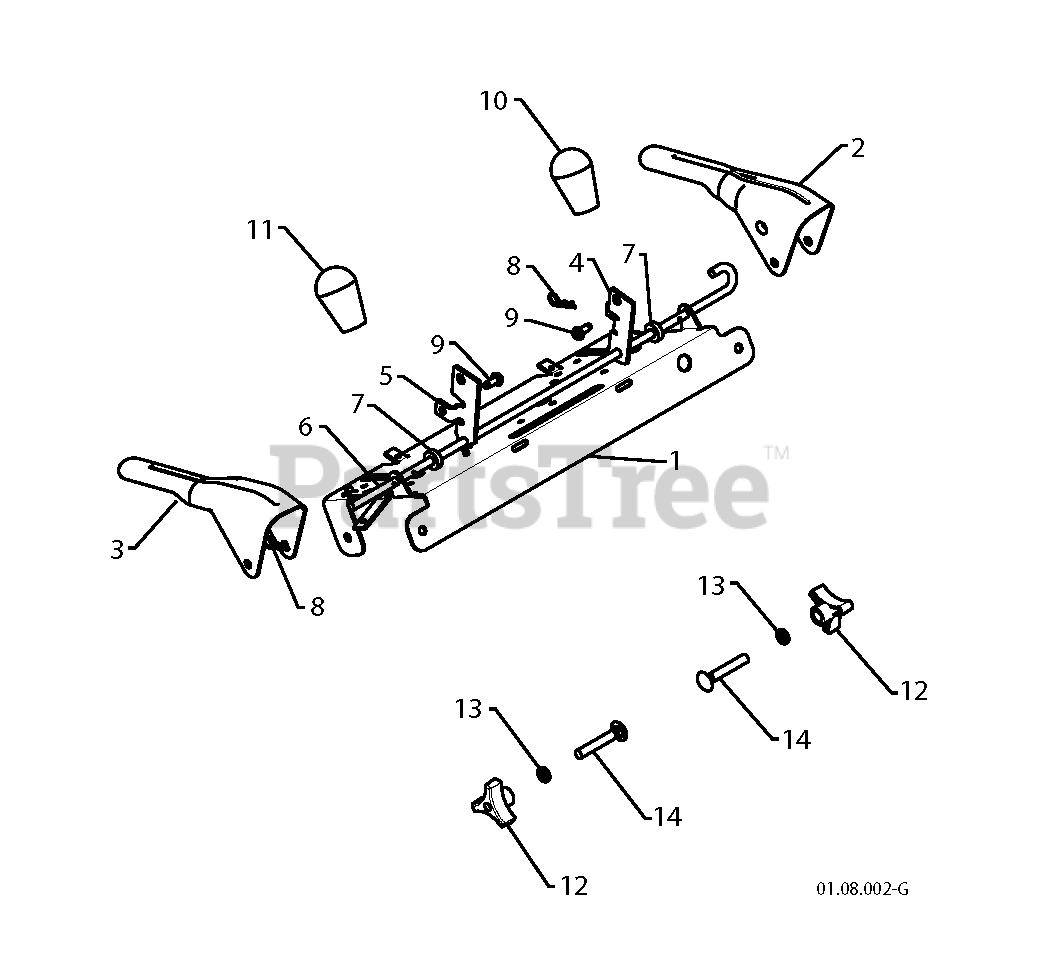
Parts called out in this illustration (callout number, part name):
1	PANEL.CONTROL.PNT.BLACK
2	LEVER.CONTROL.LH.BLACK
3	LEVER.CONTROL.RH.PNT.BLACK
4	ARM.TRACTION.ROD.YZ
5	ARM.IMPELLER.ROD.
6	BAIL.CONTROL.INTERLOCK
7	SPACER.CONTROL.LEVER
8	SPRING RETAINER
9	SCREW 14-20 X 5/8
10	KNOB LEVER, BLACK
11	RED KNOB SHIFTER
12	KNOB.HANDLE.3/8.TRI-POINT.BLAC
14	BOLT 3/8-16 X 2-1/4
